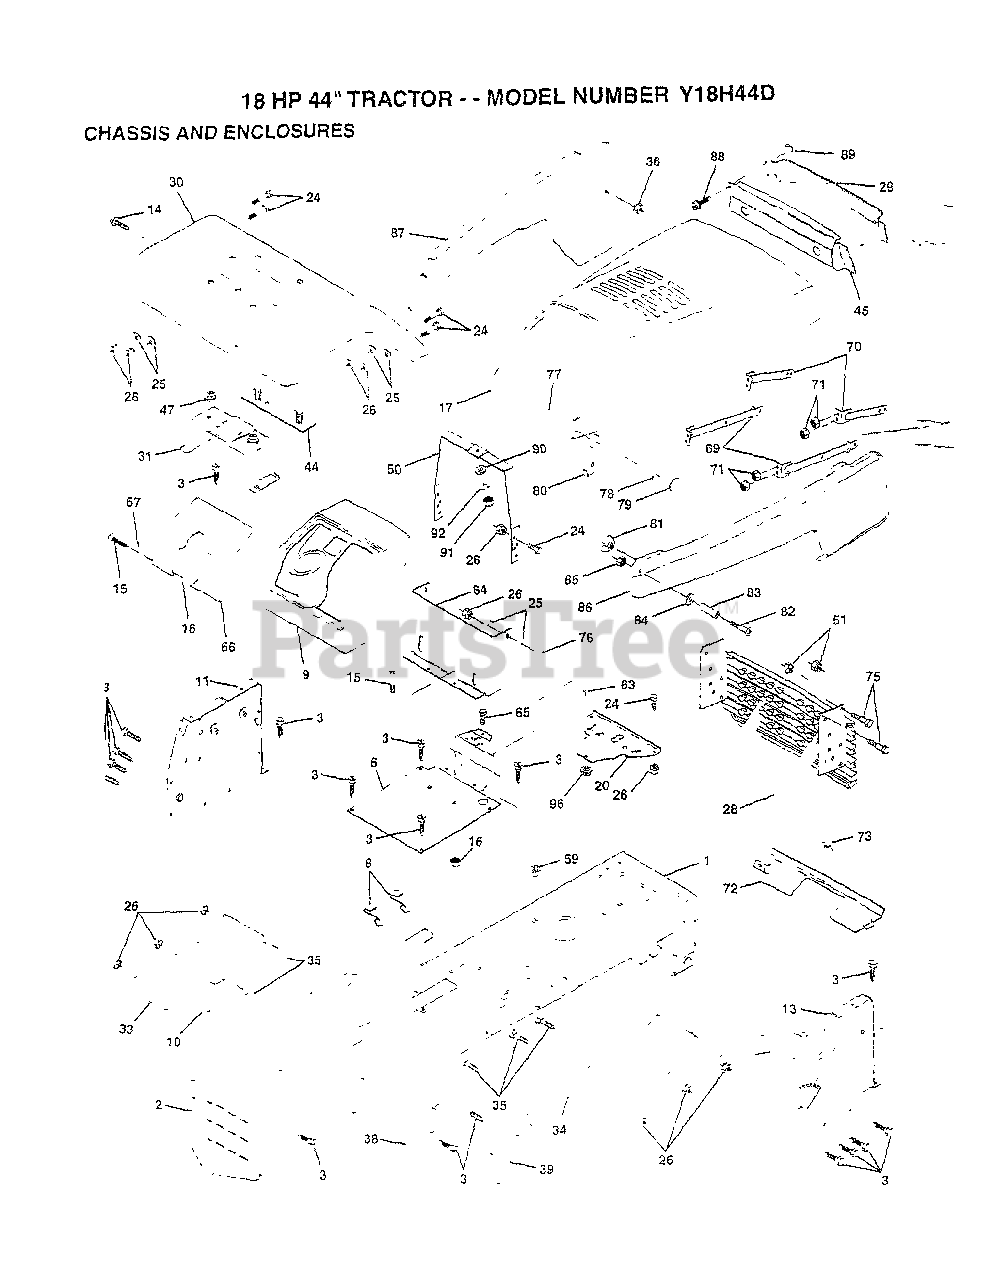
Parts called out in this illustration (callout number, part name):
3	SCREW
8	"CLIP,INSULATOR"
9	DASHBOARD BLACK
11	PANEL.DASH.LH
13	PANEL.DASH.RH
14	SCREW LT
15	SCREW
20	PLATE.SUPT.BATTER
24	BOLT
25	WASHER
26	NUT
29	LENS LT
30	FENDER.PNT.
31	BRKT.ASM.FENDER
35	BOLT
36	PAL NUT LT
38	BRACKET ASM LH
39	BRACKET ASM RH
44	STRAP ASM FENDER
47	NUT-PUSH YT
50	SUPPORT ASS'Y
51	NUT
63	SPACER
64	LOWER DASH
65	BOLT
66	PLATE SLKSCR YP
67	WASHER
71	NUT HXKEP 1/4X20
72	STRAP.GRILLE.PNT.
73	SCREW CRT
76	BOLT
77	SCREW
78	LOCKWASHER
79	WELDNUT
80	HOOD LATCH T
82	SCREW
83	SPACER LT
84	WASHER
86	PANEL SIDE RH
89	"""J"" FASTENER LT"
90	WASHER PM
92	LOCKWASHER
96	NUT
